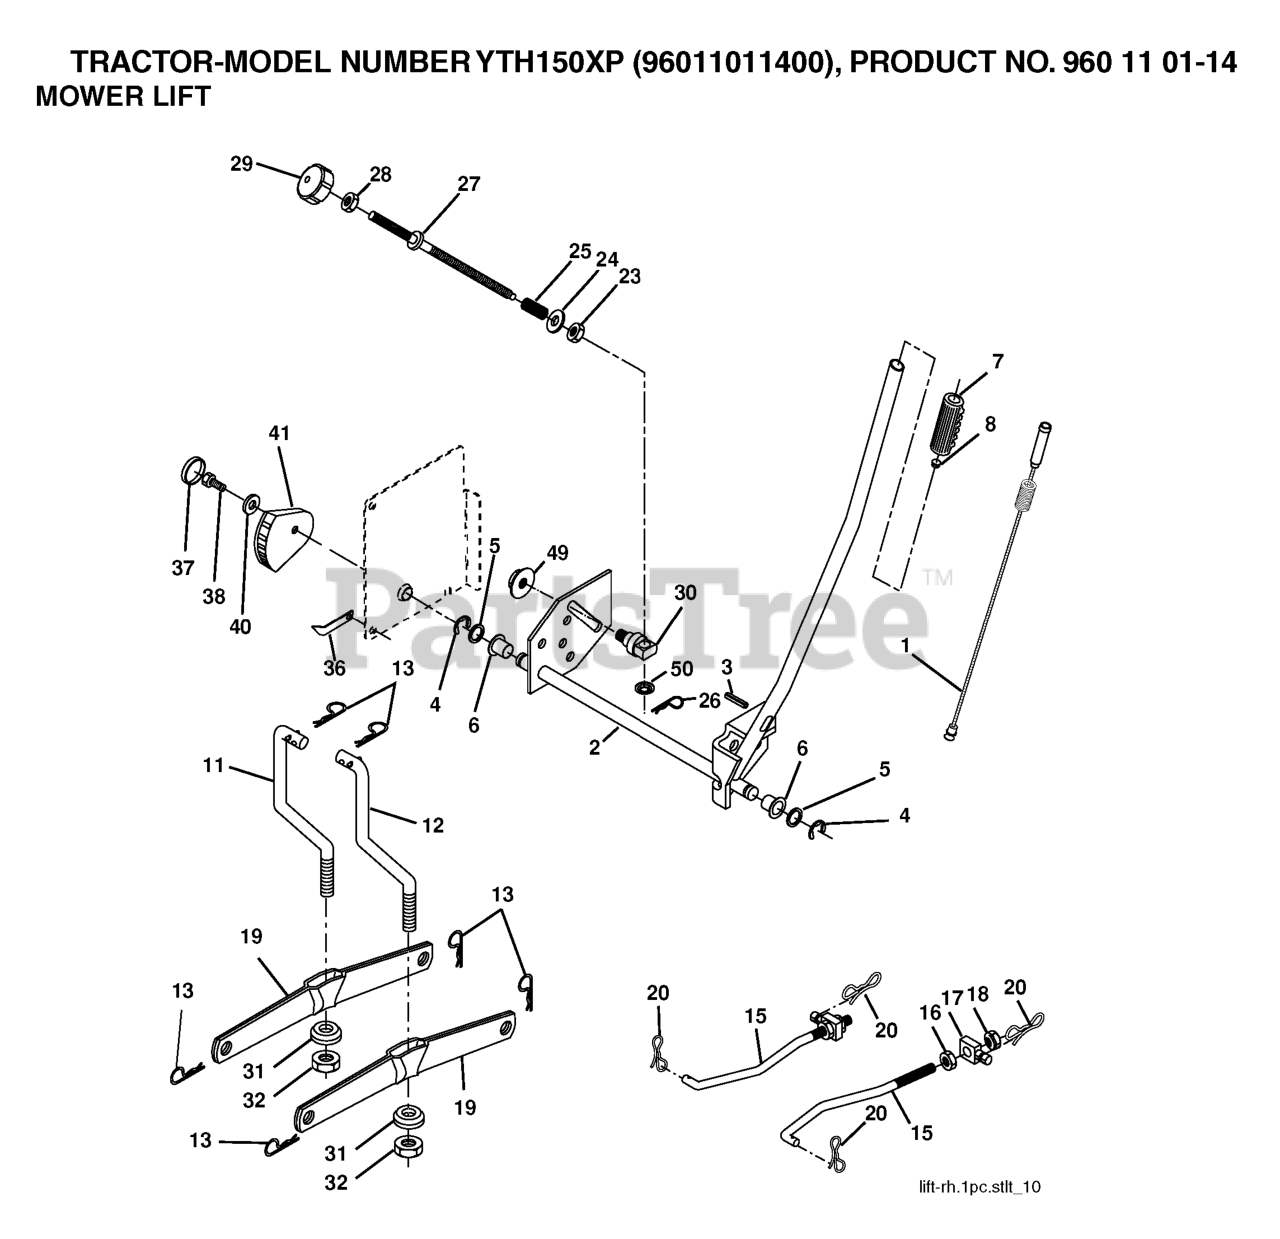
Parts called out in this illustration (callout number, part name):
1	WIRE ASM INNER W/ PLUNGER LT
2	SHAFT ASM R HANDLE
3	PIN GROOVE.
4	RETAINING RING LT
6	BEARING.NYLON
7	GRIP HANDLE
8	PLUNGER BUT KIT
11	LINK LIFT LH
12	LINK LIFT RH
13	RETAINER-SPRNG RB
15	LINK.SUSPENSION.FRONT
16	NUT.HEX.JAM.1/2-13
18	NUT.LK.W/WSH.1/2.
19	ARM.REAR.SUSPENSION
20	PIN.COTTER.7/16.BOW TI.
25	SPRING**
26	RETAINER CLIP
27	ROD ADJ LIFT
28	NUT
29	KNOB INF 3/8-16
31	BEARING.PIVOT.LIFT
32	NUT CROWNLOCK 3/8-24
36	POINTER, HEIGHT INDICATOR(2 2)
38	SCREW 5/16-18X1
41	IND. HEIGHT STLT
49	NUT
50	NUT PUSH M
